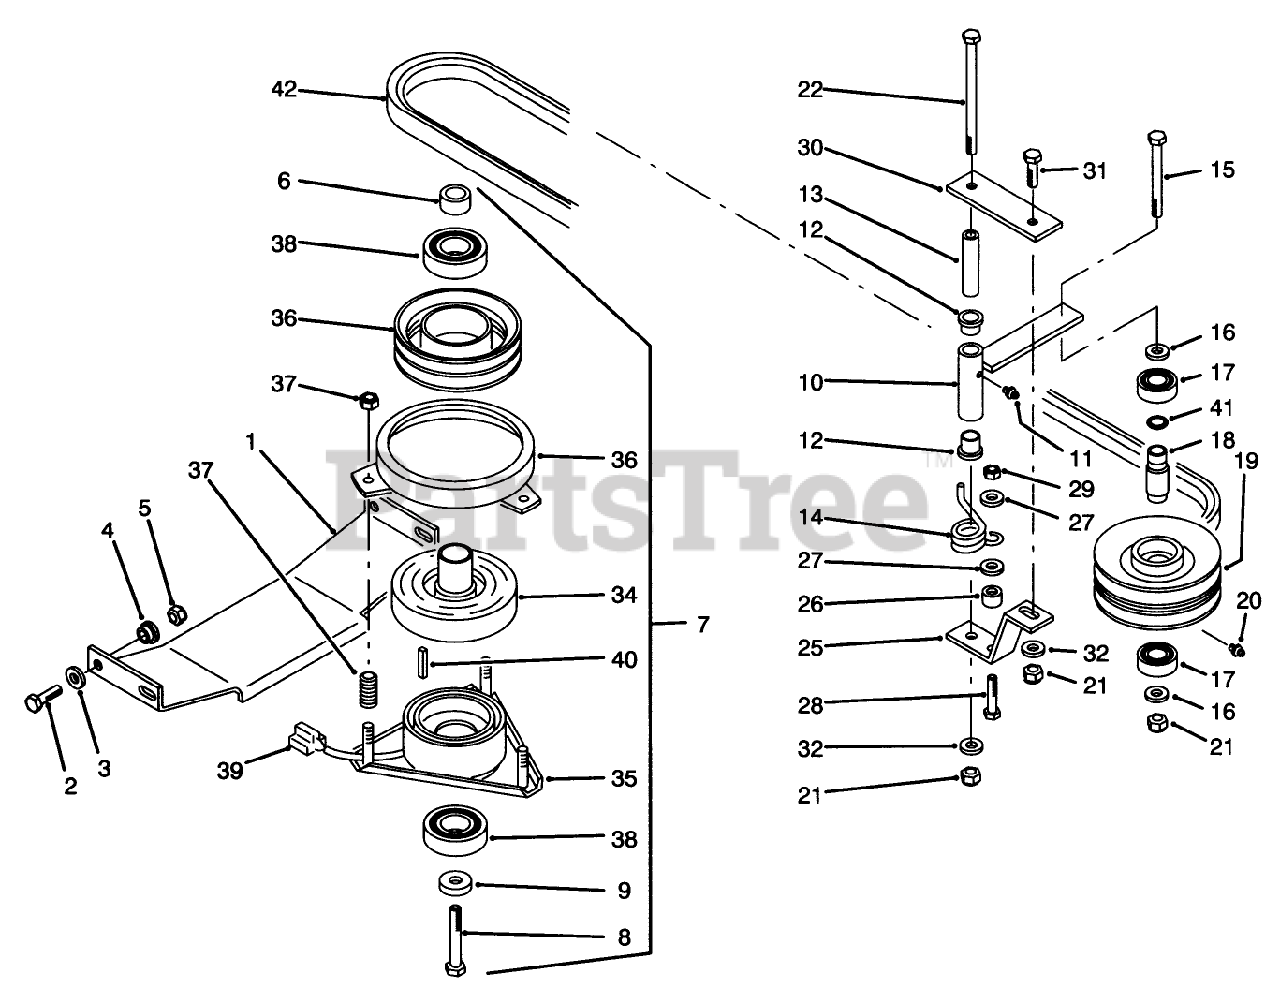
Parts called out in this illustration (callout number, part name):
1	BRACKET CLUTCH ST *R
2	SCREW-HH
3	WASHER-PLAIN
4	BUSHING
5	NUT-LOCK, NI
6	SPACER
8	SCREW-HH
9	WASHER
12	BUSHING
13	SPACER
14	SPRING-TORSION
15	SCREW-HH
17	BEARING-BALL
18	SPACER-PTO IDLER
19	PULLEY 2- GROOVE
20	FITTING-GREASE
21	NUT-LOCK, NI
22	SCREW-HH
25	Bracket-Idler
26	BEARING CAM ROLLER
27	WASHER-FLAT
28	SCREW-HH
29	NUT-LOCK, NI
31	SCREW-HH
32	WASHER-FLAT
37	ACCESS SPRING & NUT
38	BEARING-ELEC CLUTCH
39	CONNECTOR BODY *B
41	O RING
42	V-BELT
